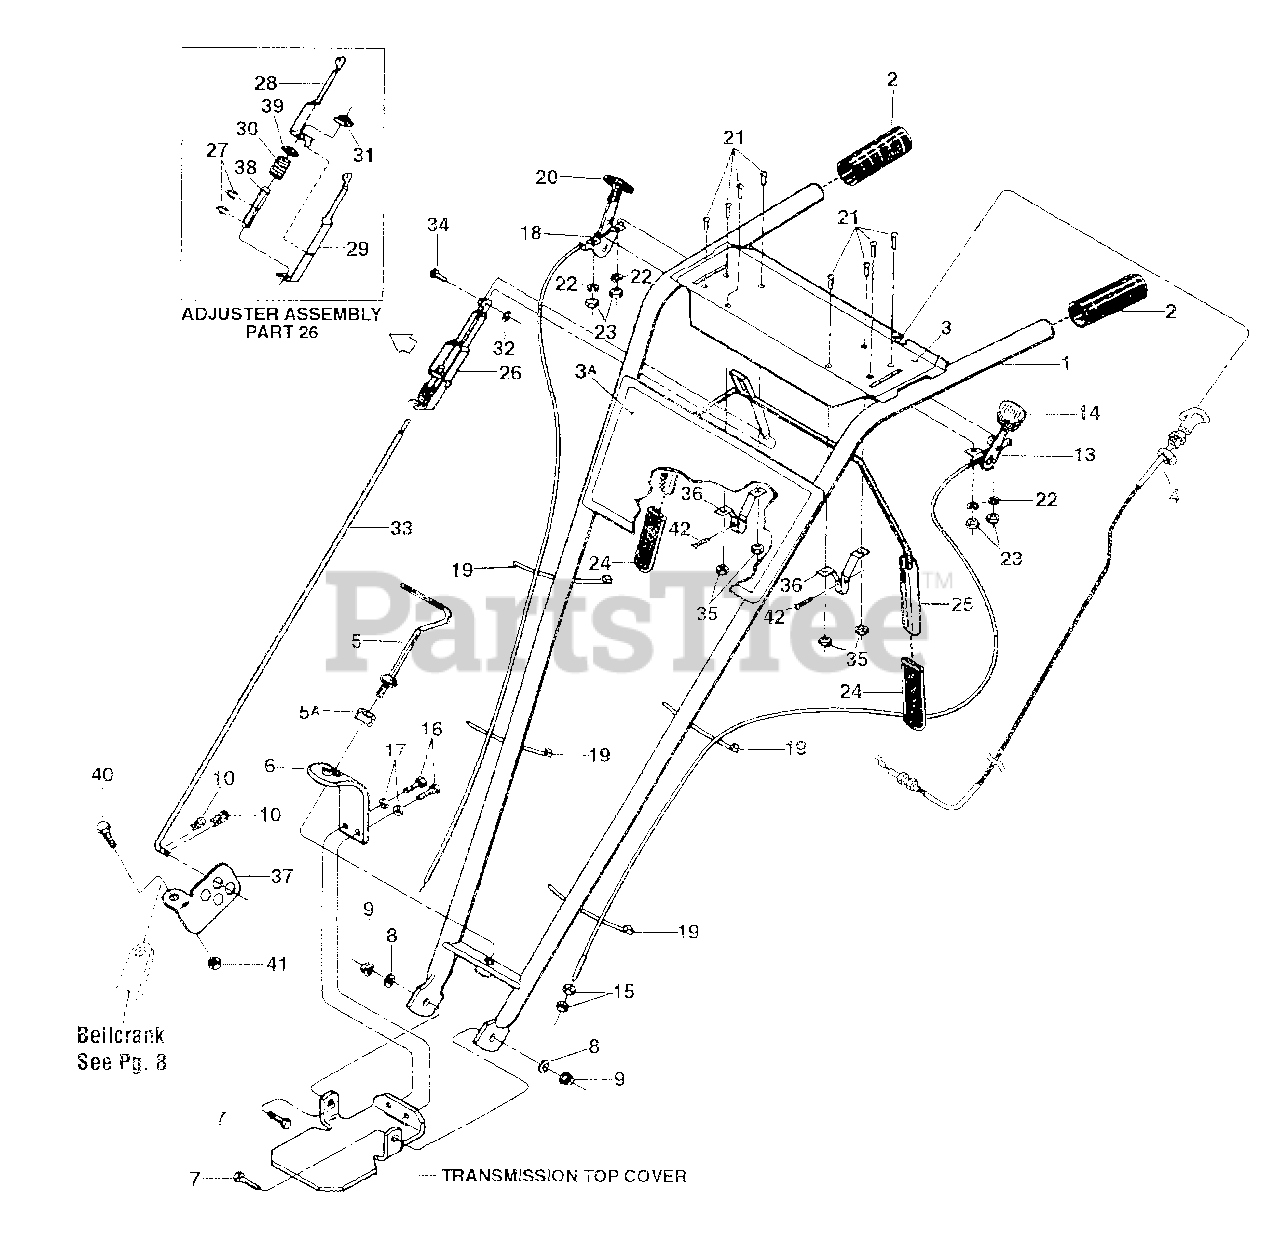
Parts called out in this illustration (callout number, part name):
1	Handlebars-
2	Grip-handlebars
3	Decal-for operator control panel
3A	Decal-Troy-Bilt Pony (model name, logo)
4	Reverse Clutch Control Cable
5	Handle, Height Adjustment
5A	Washer-keyed
6	Bracket-handlebar height adjust
7	Screw-hex hd., 3/8-16 x 1
8	Washer-plain (flat) 3/8, S.A.E
9	Locknut-hex, 3/8-16
10	Hair Pin Cotter
13	Wheel Gear Control & Cable Assy.
14	Knob-wheel gear control lever
15	Nut-hex, 5/16-24, wheel gear cable adjustment
16	Screw-hex hd., 3/8-16 x 3/4
17	Lockwasher-3/8
18	Engine Throttle Control & Cable
19	Ties-plastic
20	Knob-throttle control lever
21	Screw-round hd, No. 10-32 x 1/2
22	Lockwasher-No.10
23	Nut-hex, No. 10-32
24	Grip-paddle
25	Bail-forward clutch control
26	Adjuster Assembly
27	Klip Ring
28	Adjuster, Right Side
29	Adjuster, Left Side
30	Spring-Adjuster
31	Nut-rectangular
32	Klip Ring
33	Rod-forward clutch
34	Pin-Clevis
35	Sems Nut
36	Bracket-bail support
37	Swivel
38	Bushing
39	Washer
40	Screw-hex hd., 1/4-20 x 3/4
41	Nut-1/4-20
42	Screw-flanged hex hd, self-tapping, 1/4-20 x 1/2
